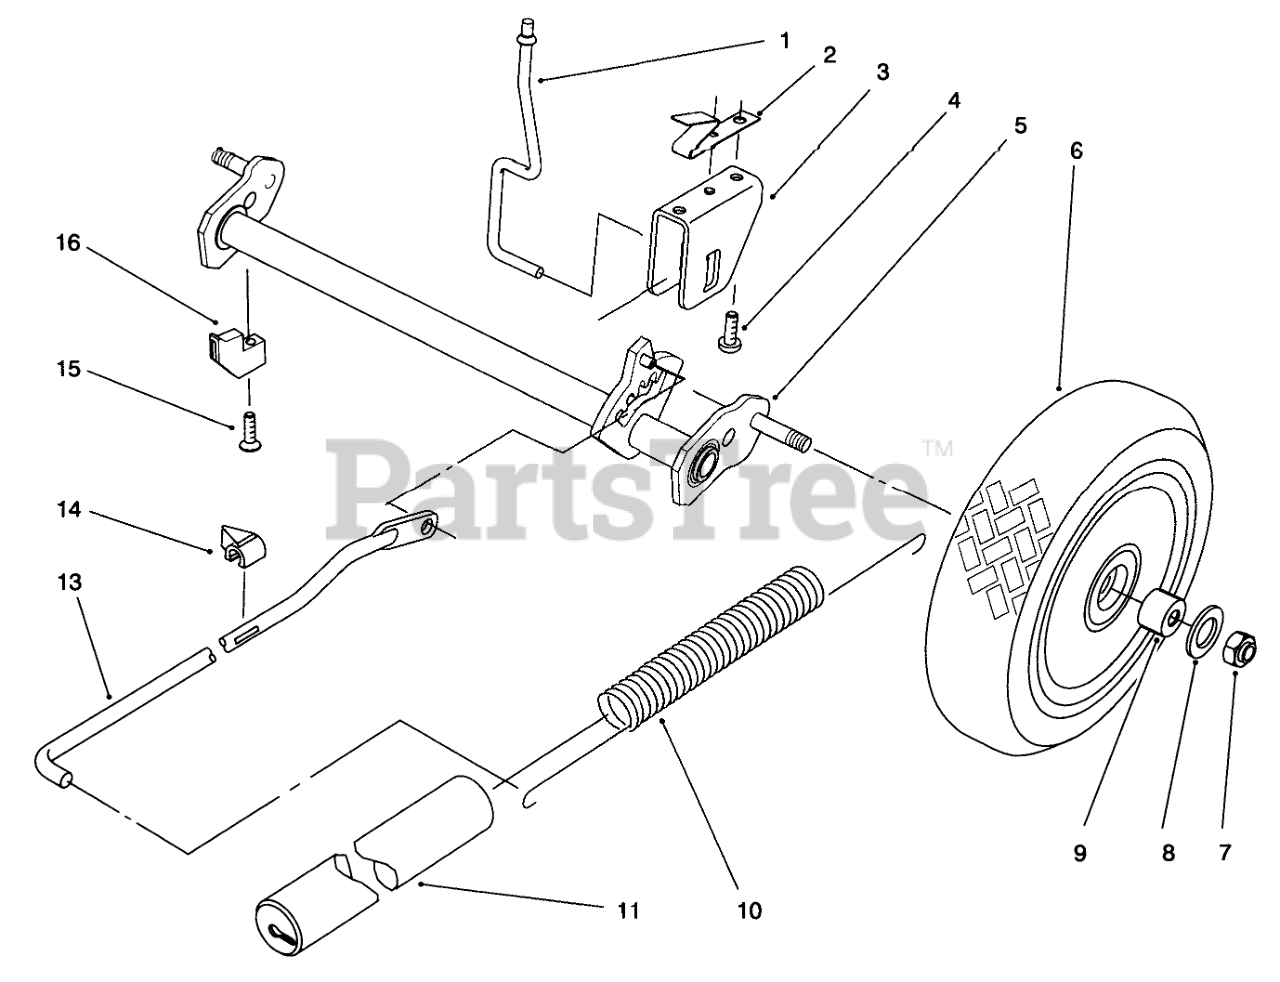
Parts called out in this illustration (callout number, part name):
1	Rod-Trigger
2	SPRING-RETURN, TRIGGER
3	SADDLE-HEIGHT OF CUT
4	SCREW-RH
5	AXLE-REAR
6	WHEEL-REAR
7	NUT-HH
8	WASHER-WHEEL
9	BUSHING
10	SPRING-COUNTERBALANCE
11	COVER-SPRING
13	ROD-LINK
14	INDICATOR-HEIGHT OF CUT
15	SCREW-RETAINER
16	RETAINER - AXLE
